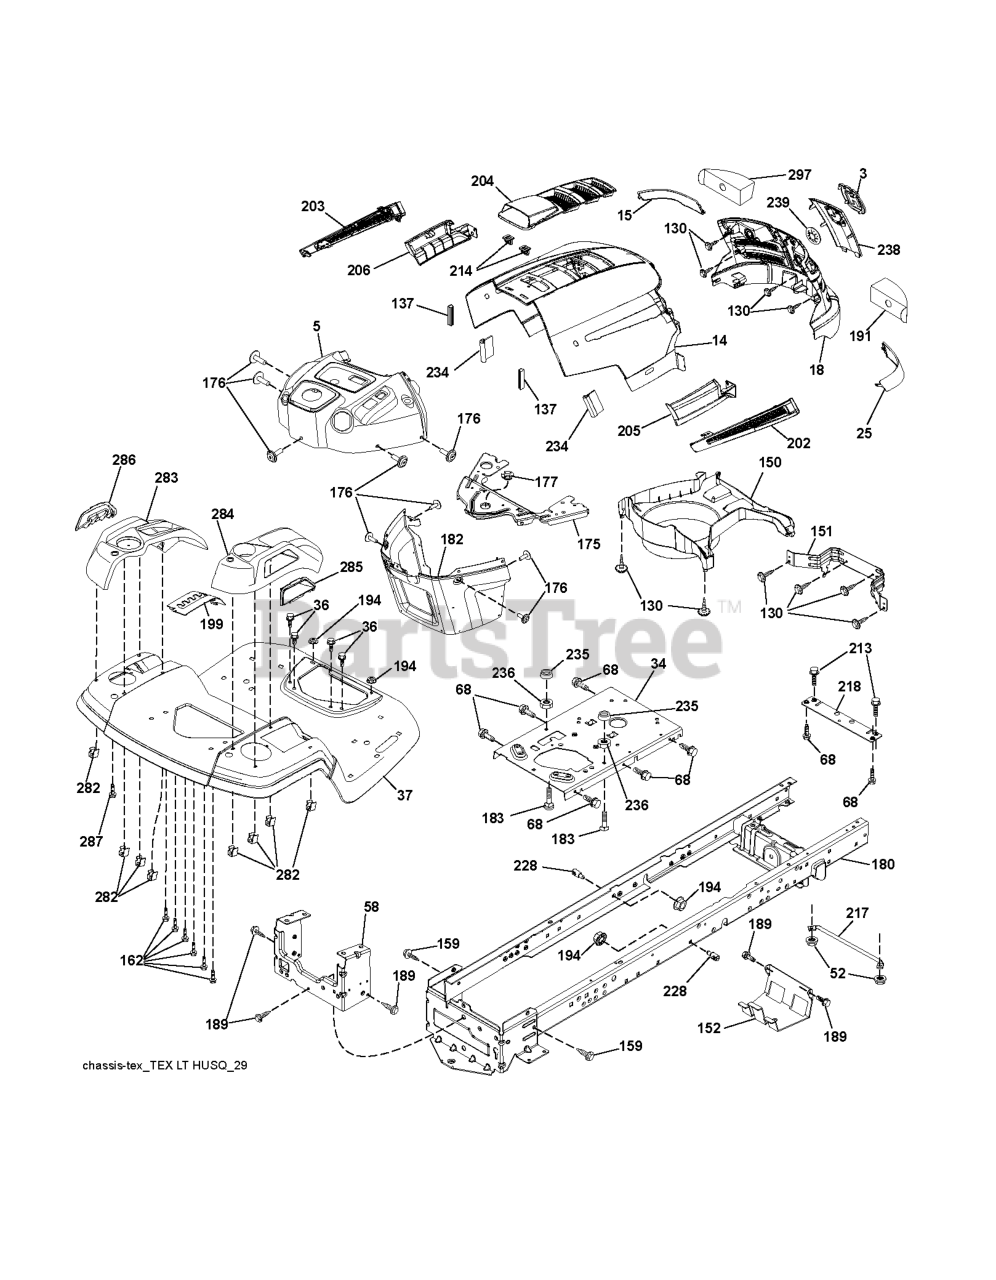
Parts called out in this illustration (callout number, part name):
3	RP LOGO
5	DASH
14	HOOD.HUSQVARNA.LT.ORANGE
15	LENS.HUSQVARNA LT.LH
18	GRILLE.SVC.HUSQVARNA.LT.GREY
25	LENS.HUSQVARNA LT.RH
34	PLATE.ENGINE.WELDED.CHASSIS
36	SCREW 5/16"
37	FENDER.TLT.FS.W/CUPHLD.ORANGE
52	LOCKNUT
58	DRAWBAR UPPER 2PC SMALL FENDER
68	Screw 5/16-18 x 1/2 Hex, Self Tapping 5/16-18 x 1/2
130	SCREW.#10 X 0.750.BOS
137	BUMPER DASH
151	BRACKET PIVOT
152	SHIELD.BROWNING.W/TEX
159	SCREW, 3/8-16X3/4
162	SCREW.HI-LO.CONSOLE
175	CROSSMEMBER
176	SCREW.#10-24X5/8.RN.QU
177	BUSHING STEERING
180	CHASS.WLDMNT.TL.12GA/2P.48/54
182	DASH.LOWER.PREDATOR LT
183	BOLT.5/16-18X1-1/4 FULL THD
189	SCREW
191	INSERT REFLECTIVE
194	NUT LOCK HEX FLANGE 5/16-18
199	PLATE.DECK.LIFT.HUSQ.LT
202	VENT SIDE HOOD LH
203	VENT SIDE HOOD RH
204	VENT TOP HOOD
205	SKIRT SIDE RH
206	SKIRT SIDE LH
213	BOLT
214	CLIP.RETAINER.TINNER.
217	ROD.PIVOT.HOOD
218	X-PIECE.HOOD.STOP.NON/
228	STUD.FASTNER.W/ANTI-ROTATE
234	BUMPER.HOOD.TEX.HUSQVARNA
235	SPACER FENDER
236	NUT.CENTERLOCK.5/16-
238	TRIM
282	CLIP.RETAINER.CONSOLE.LT.HUSQ
283	CONSOLE.ASM.LFT.NFR.HUSQ.LT
285	CONSOLE INSERT RH
286	CONSOLE.INSRT.LH.HUSQ.LT.BLACK
287	SCREW 1/4X20
297	INSERT.REFLECTIVE.RH.
